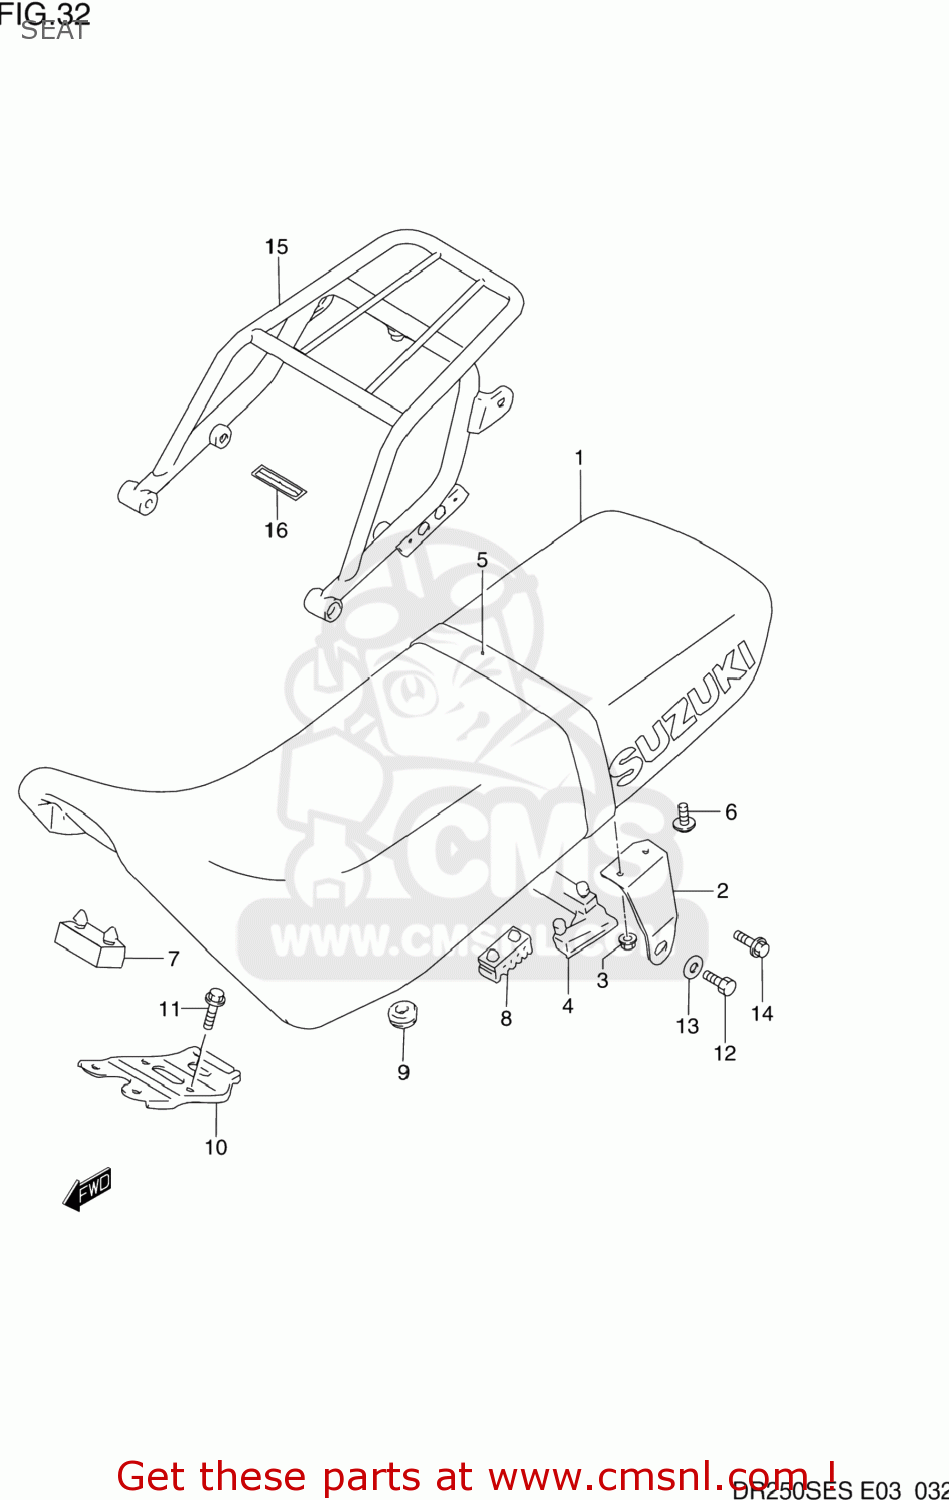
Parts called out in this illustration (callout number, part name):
1	SEAT SET
2	BRACKET,SEAT,R
3	NUT
4	CUSHION
5	BAND,SEAT GRIP (BLUE)
6	BOLT
7	CUSHION
8	CUSHION,SEAT(40X20X15)
9	CUSHION
10	PLATE,SEAT FR HOOK
11	BOLT
12	BOLT
13	WASHER
14	BOLT
15	CARRIER
16	LABEL,WARNING
